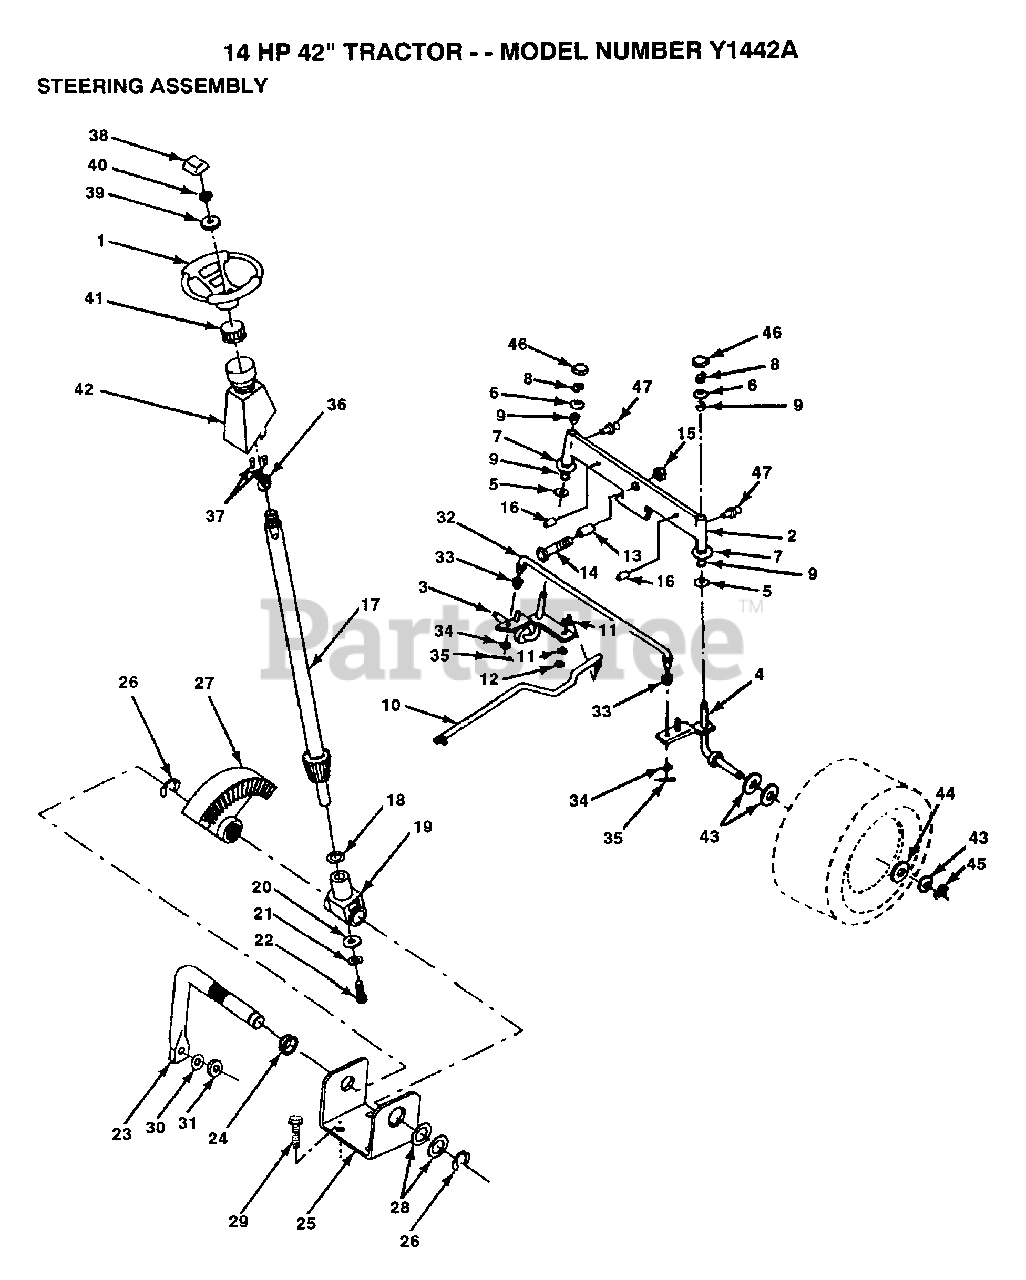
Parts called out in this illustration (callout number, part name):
3	SPINDLE LH
4	SPINDLE RH
5	WASHER .T
6	WASHER
7	WASHER
8	RING
9	COL. SRTG. BEAR.
11	LOCKWASHER
13	BEARING
14	BOLT HEX 5/8-11
16	AXLE PIN
17	SHAFT ASM
18	THRUST WASHER
19	SUPPORT.SHAFT
21	LOCKWASHER
22	"SCREW,SPECIAL"
24	NYLINER T
25	"BRKT,STEERING"
26	RING
28	WASHER .T
29	SCREW
30	LOCKWASHER
32	TIE ROD
33	BUSHING.DRAGLINK
34	WASHER
35	COTTER PIN
38	INSERT STEERING
39	WASHER T
40	GRIPCO NUT
41	ADAPTER-WHEEL LT
42	"TUBE, STR SHAFT"
43	WASHER
44	WASHER
45	RING
46	CAP
47	ZERK M
